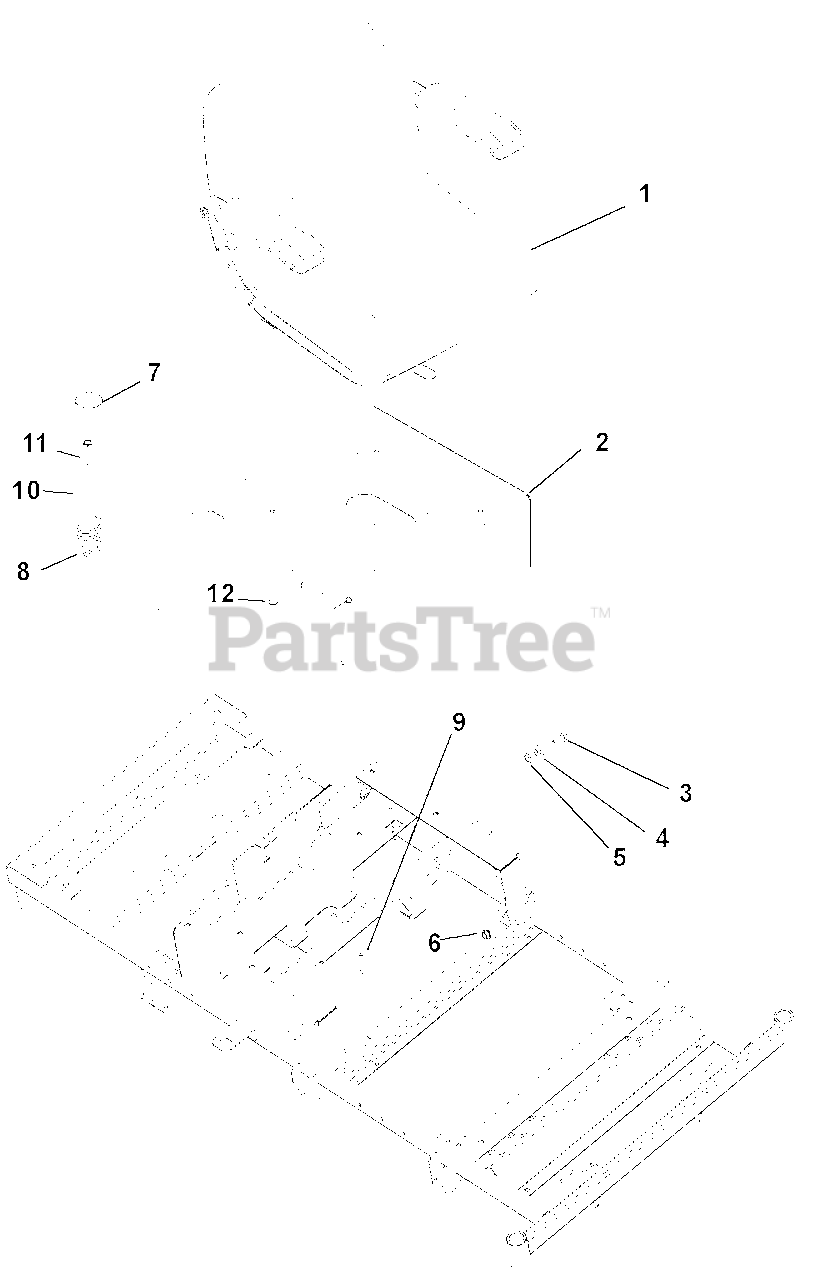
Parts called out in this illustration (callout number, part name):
1	SEAT, MILSCO XB-180
2	SEAT PLATE
3	BLT-HEX .38-16X1.00 GR5 YWZC
4	BSHG-FLG .385X.500X.875X.406
5	WSHR-FL-STL .52X.827X.062 YWZC
6	NUT-LK-NYL-FLG .38-16 YWZC
8	SPRING, SEAT
9	BLT-RDHDSQNK .31-18X1.50 G5YZ
10	WSHR-FL-STL .328X.87X.179 YWZC
11	NUT, COUPLING 5/16-18 X 1 3/4
12	NUT-LK-NYL-FLG .31-18 YWZC
